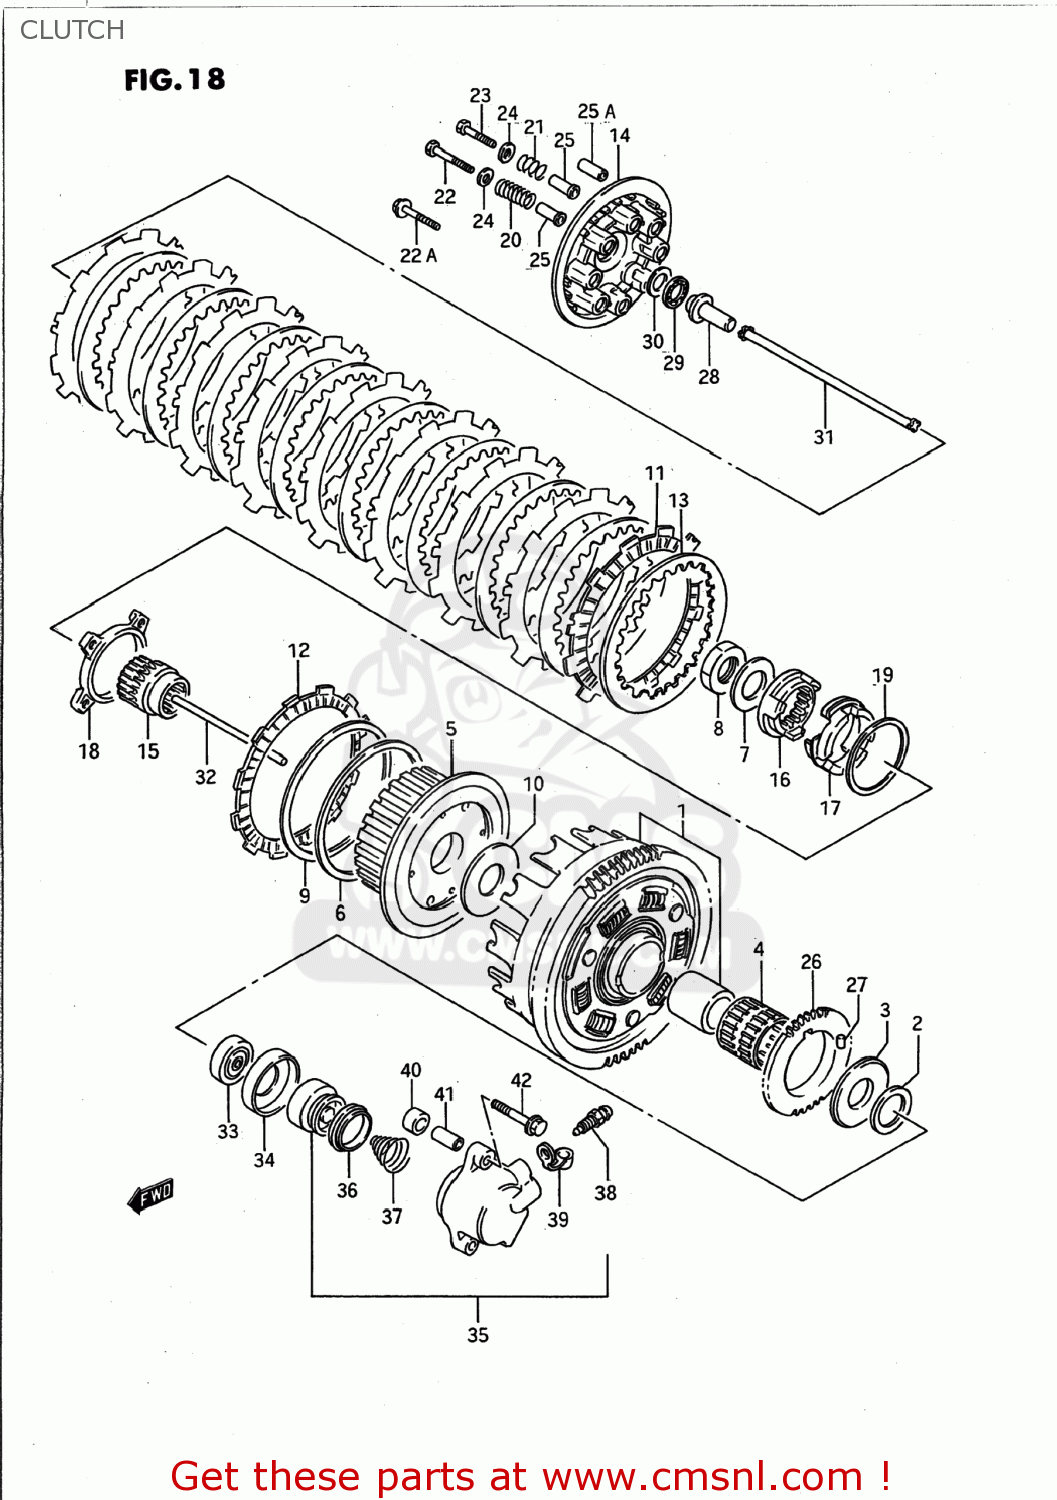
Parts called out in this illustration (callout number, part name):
1	GEAR ASSEMBLY,PRIMARY DRIVE
2	WASHER(25X38X2.5)
3	WASHER(25X54X2.5)
4	BEARING(35X40X35.8)
5	HUB,CLUTCH SLEEVE
6	SEAT,WAVE WASHER(T:1.4)
7	WASHER
8	NUT
9	WASHER
10	WASHER(25X60X2.5)
11	PLATE,CLUTCH DRIVE (NAS)
12	PLATE,CLUTCH DRIVE(T:3.5) (NAS)
13	PLATE,CLUTCH DRIVEN (NAS)
14	DISC,CLUTCH PRESSURE
15	SPACER,CLUTCH SLEEVE HUB
16	CAM,CLUTCH NO.1
17	CAM,CLUTCH NO.2
18	SLIDER,CLUTCH SPRING
19	WASHER(54X62X1)
20	SPRING
21	SPRING
22	BOLT
22A	BOLT(6X40)
23	BOLT
24	WASHER
25	SPACER(6.4X10X22)
25A	SPACER (6,1X9X24.1)
26	GEAR,OIL PUMP DRIVE
27	PIN(6X6)
28	PIECE,CLUTCH PUSH
29	BEARING(15X28X2)
30	WASHER(15.5X28X1)
31	ROD,CLUTCH PUSH,R
32	ROD,CLUTCH PUSH,L
33	SEAL,OIL(6X34X11)
34	RETAINER,CL PUSH ROD OIL SEAL
35	CYLINDER,CLUTCH RELEASE
36	CUP
37	SPRING,CLUTCH CYLINDER
38	BLEEDER
39	CAP,BLEEDER
40	SPACER(9X16X11)
41	PIN(6.4X9X23)
42	BOLT
